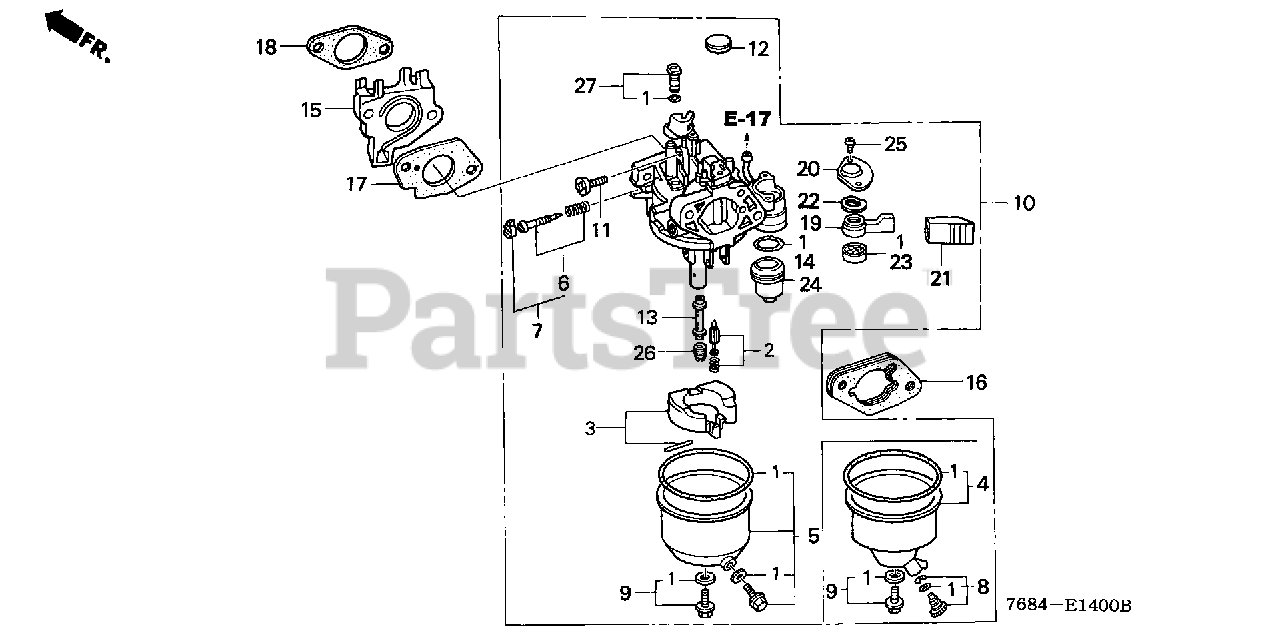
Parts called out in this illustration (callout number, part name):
1	GASKET SET
2	VALVE SET, FLOAT
4	CHAMBER SET, FLOAT
7	SCREW SET, PILOT
8	SCREW SET, DRAIN
9	SCREW SET
10	CARBURETOR ASSY. (BE70G A)
11	SCREW, THROTTLE STOP
12	CAP, CHOKE DUST
13	NOZZLE, MAIN
14	GASKET, FUEL STRAINER CUP
15	INSULATOR, CARBURETOR
16	SPACER, CARBURETOR
17	GASKET, CARBURETOR
18	GASKET, INSULATOR
19	LEVER, PETCOCK
20	PLATE, LEVER SETTING
21	CAP, LEVER
22	SPRING, PETCOCK LEVER
23	GASKET, PETCOCK
24	CUP, FUEL STRAINER
25	SCREW, PAN (3X6)
26	JET, MAIN (#90)
26	JET, MAIN (#88)
26	JET, MAIN (#92)
27	JET SET, PILOT (#38)
